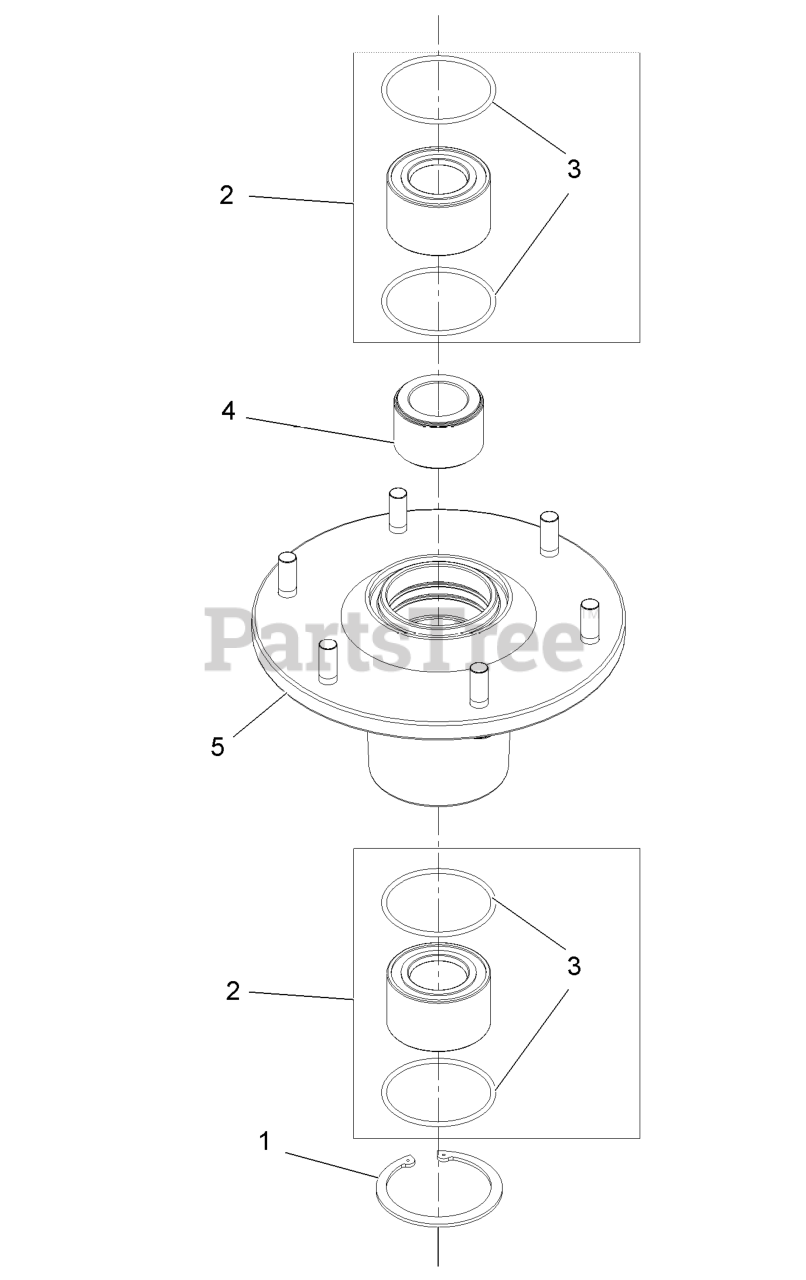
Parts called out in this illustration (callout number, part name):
1	RING-RETAINING
2	ASM, BEARING W/ORINGS
4	SPACER,BEARING
5	ASM,HOUSING W/STUDS
